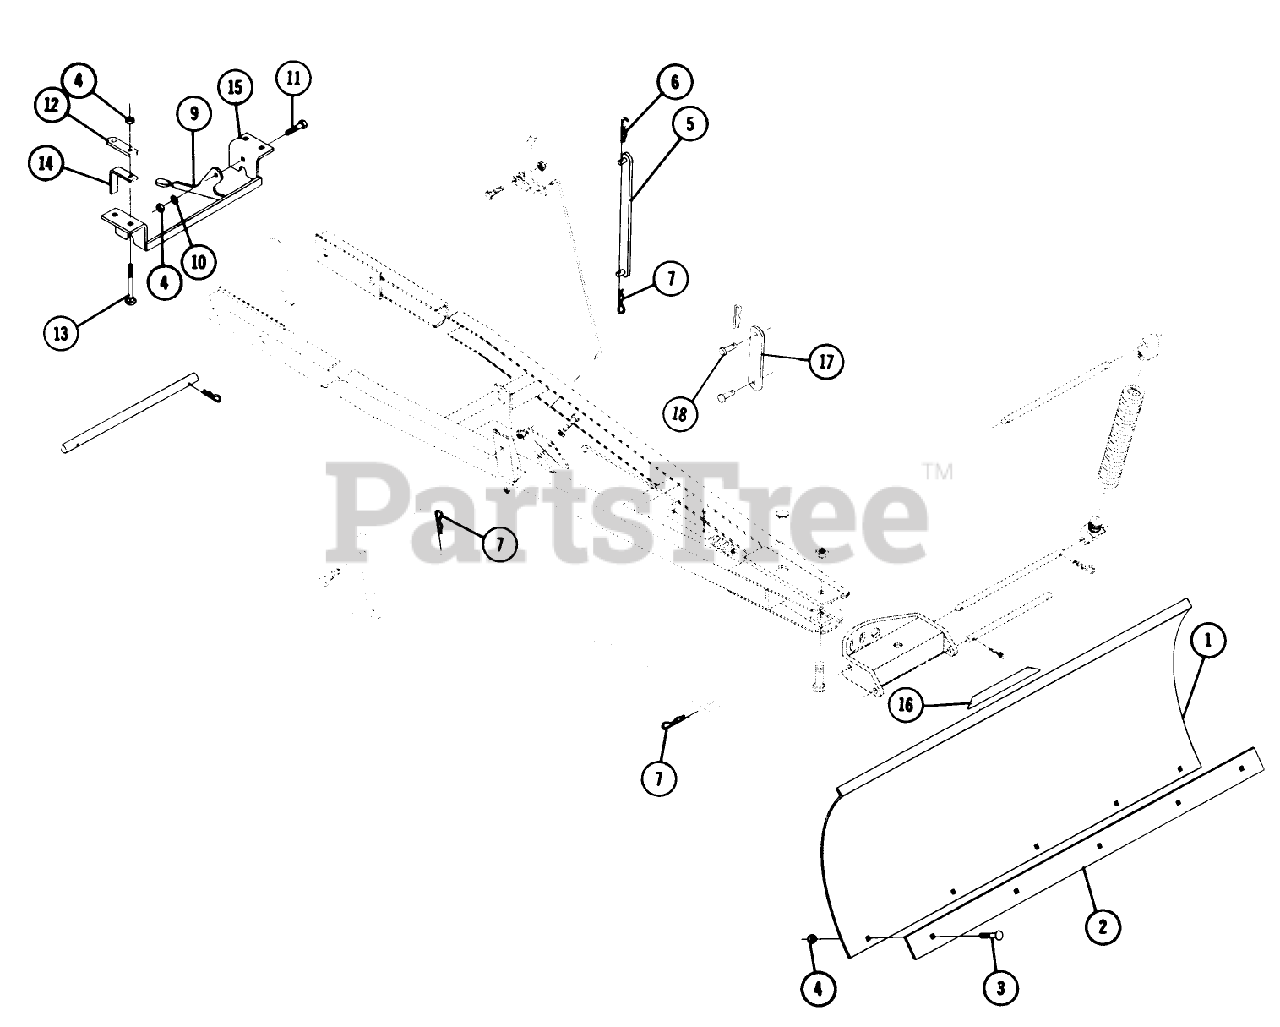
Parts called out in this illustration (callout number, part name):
1	Blade
2	Plate
3	Bolt-Carriage
4	NUT
5	LIFT BAR ASSY R
6	Hairpin Cotter
7	Hairpin
9	Latch Hitch
10	Washer
11	BOLT
12	BRACKET-REAR LINK MOUNTING
13	Bolt-Carriage
14	SPACER-BRACKET
15	Bracket
16	DECAL-WHEEL HORSE
17	Link-Short
18	Pin
